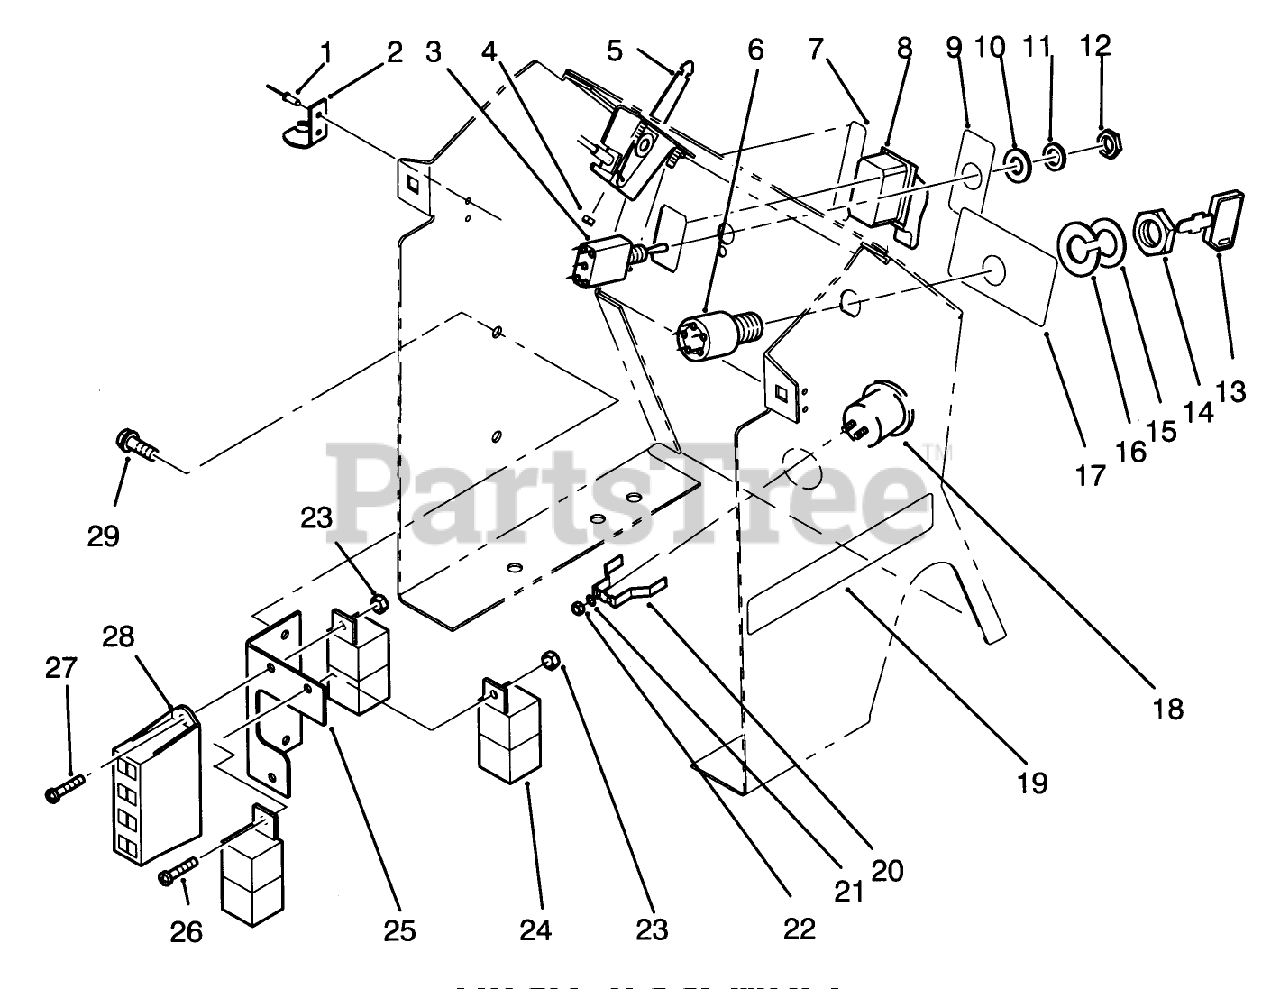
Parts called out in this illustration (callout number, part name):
1	POPRIVET 1/8X 1/8 BK
2	KEEPER-LATCH
3	SWITCH-LIGHTS
4	Nut
5	CONTROL-THROTTLE
6	Switch-Ignition, (Incl. Ref #6 & 13-17)
7	DECAL-PTO
8	PTO-SWITCH W/COVER
9	DECAL-LIGHTS
10	WIRE ASSY
11	Washer
13	KEY-IGNITION
15	Washer
16	LOCKWASHER
17	DECAL-IGNITION
18	HOUR-METER
19	DECAL-MODEL 5-SPEED
20	CLAMP-HOUR METER
21	WASHER-LOCK
22	Nut
23	Nut
24	RELAY
25	Bracket-Fuse Holder
26	SCREW-PPH
27	Screw
28	FUSE-HOLDER 4 WAY
29	TRS-1/4-20X1/2 BLACK
